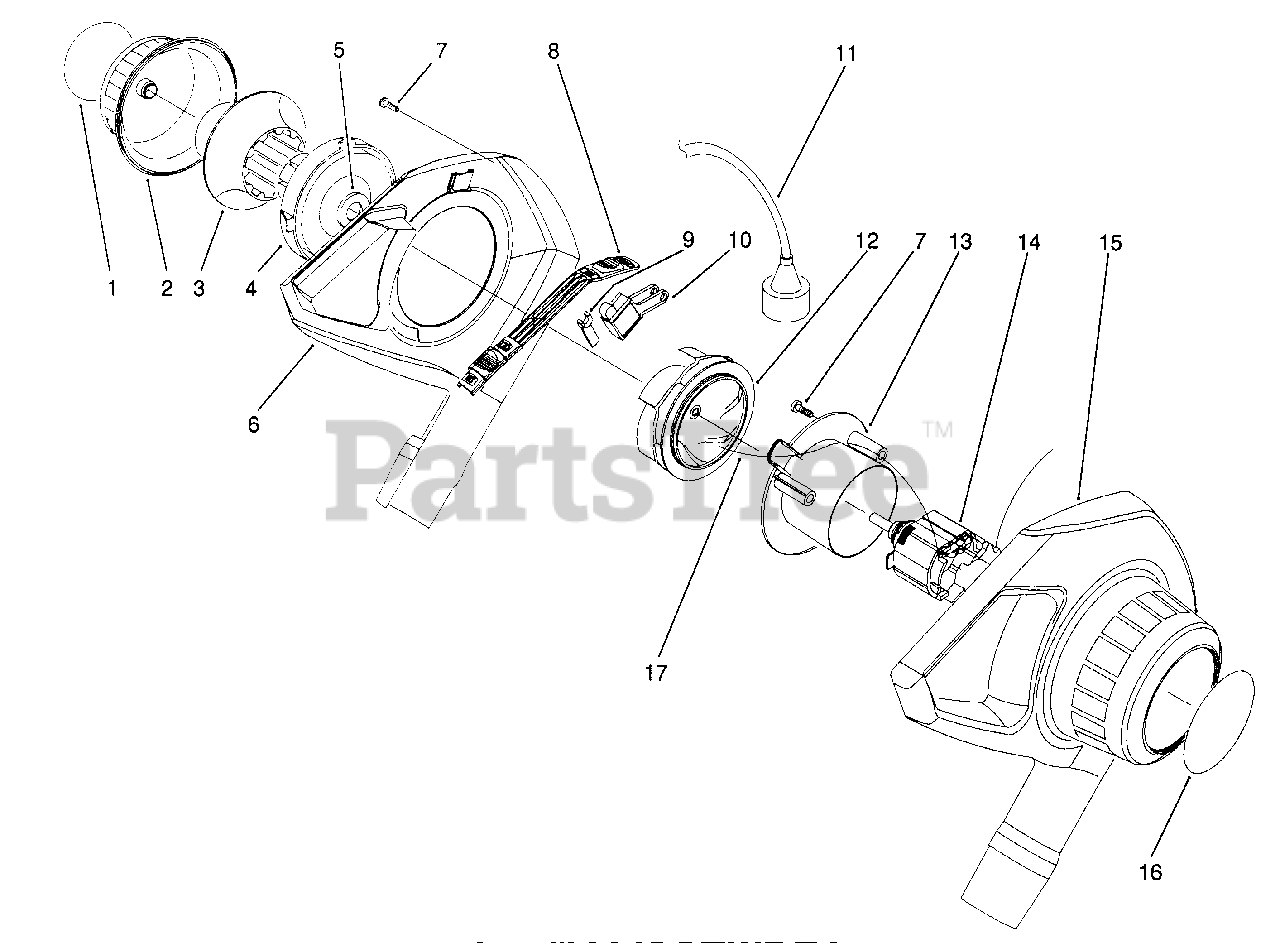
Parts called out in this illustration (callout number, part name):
1	Decal-Choke
2	Cover-Choke
3	Ring-Choke
4	Base-Choke
5	Clip-Retainer
6	Housing Assembly-R.H.
7	Screw
8	Bar-Switch
9	Lever-Actuating
10	Switch
11	Cord-Power
12	Impeller Assembly
13	Plate-Retaining
15	Housing-L.H.
16	Decal-Motor Cover
